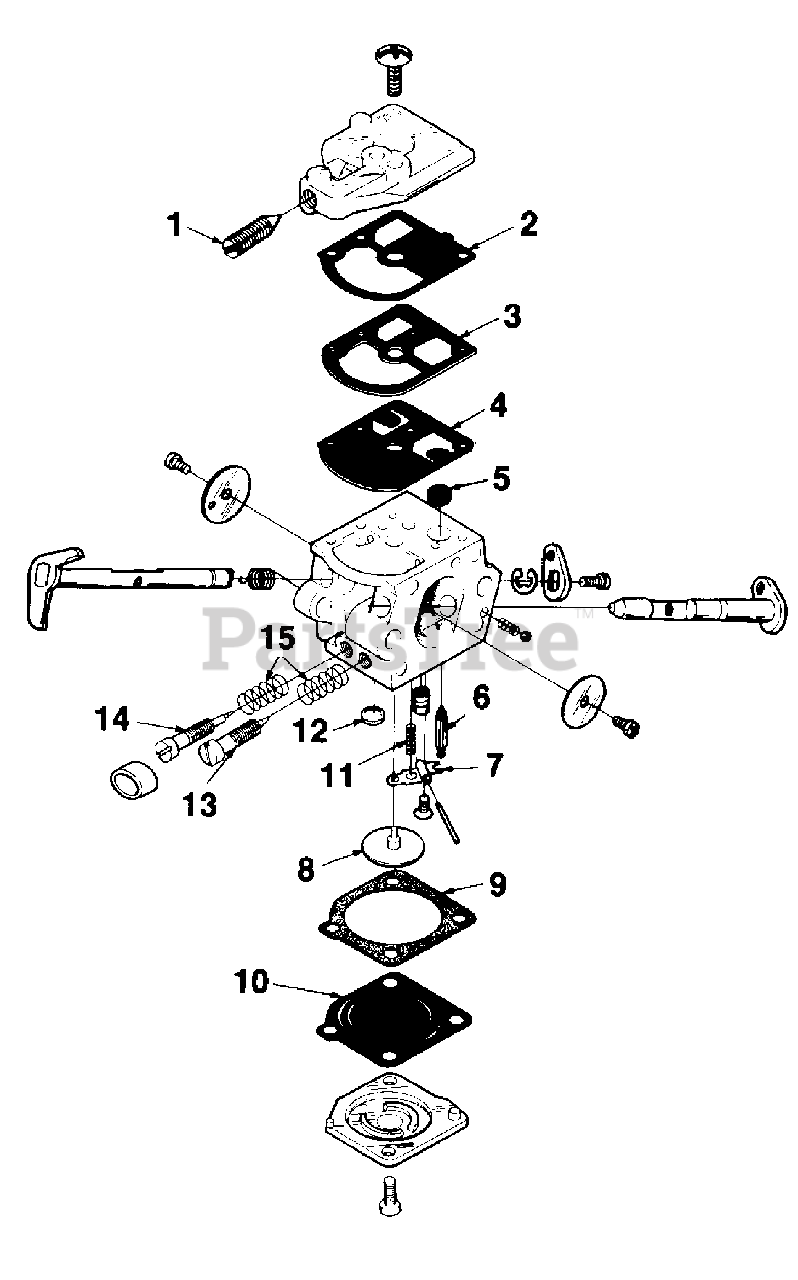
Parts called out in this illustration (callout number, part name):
1	Repair Kit
2	Repair Kit
3	Repair Kit
4	Repair Kit
5	Repair Kit
6	Repair Kit
7	Repair Kit
8	Repair Kit
9	Repair Kit
10	Repair Kit
11	Repair Kit
12	Repair Kit
13	Repair Kit
14	Repair Kit
15	Repair Kit
